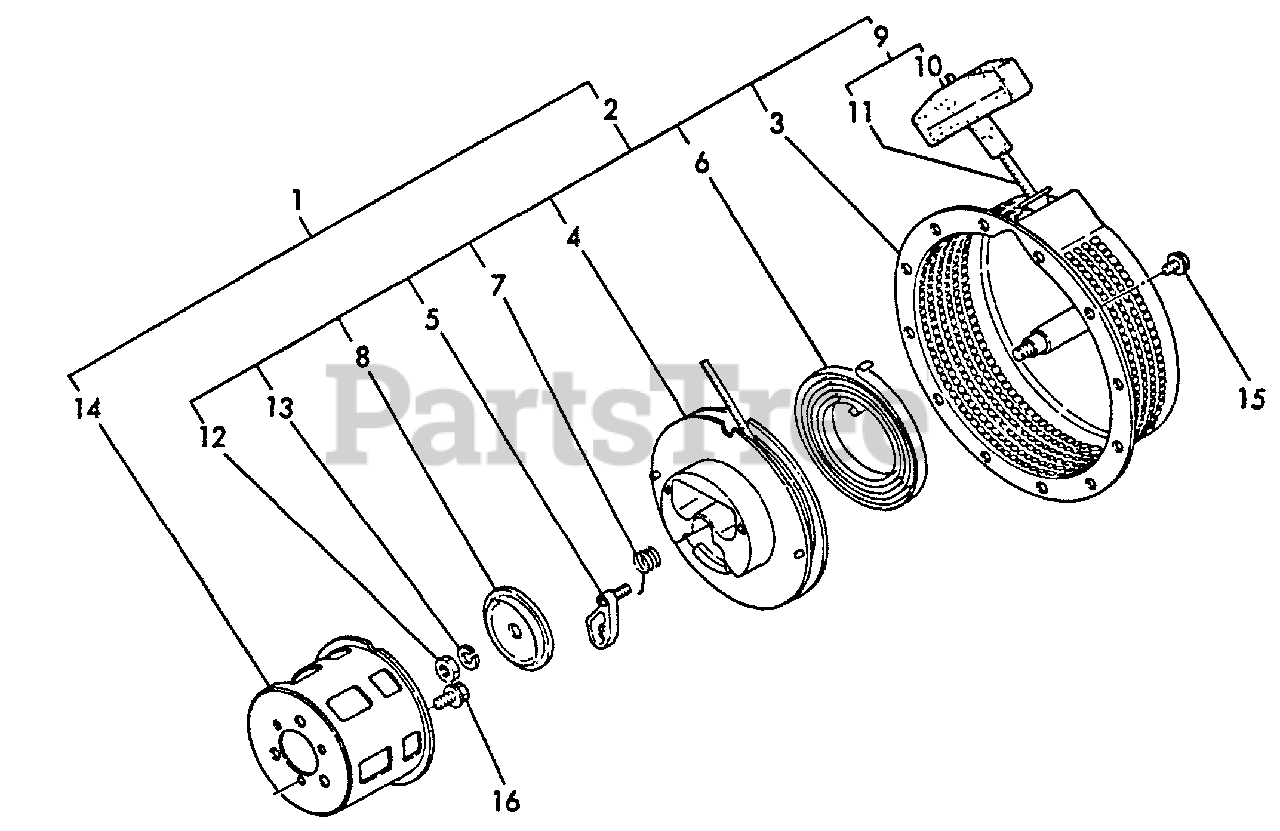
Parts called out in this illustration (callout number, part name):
1	STARTER ASSY
2	RECOIL ASSY
3	CASE, STARTER
4	PULLEY
5	RATCHET
7	SPRING, FRICTION
8	PLATE
9	ROPE ASSY
10	GRIP, STARTER
11	STARTER WIRE
12	NUT
13	LOCKWASHER
14	PULLEY, STARTER
15	BOLT - 6×8 -- PLATED
16	BOLT - 6×12 -- PLATED
